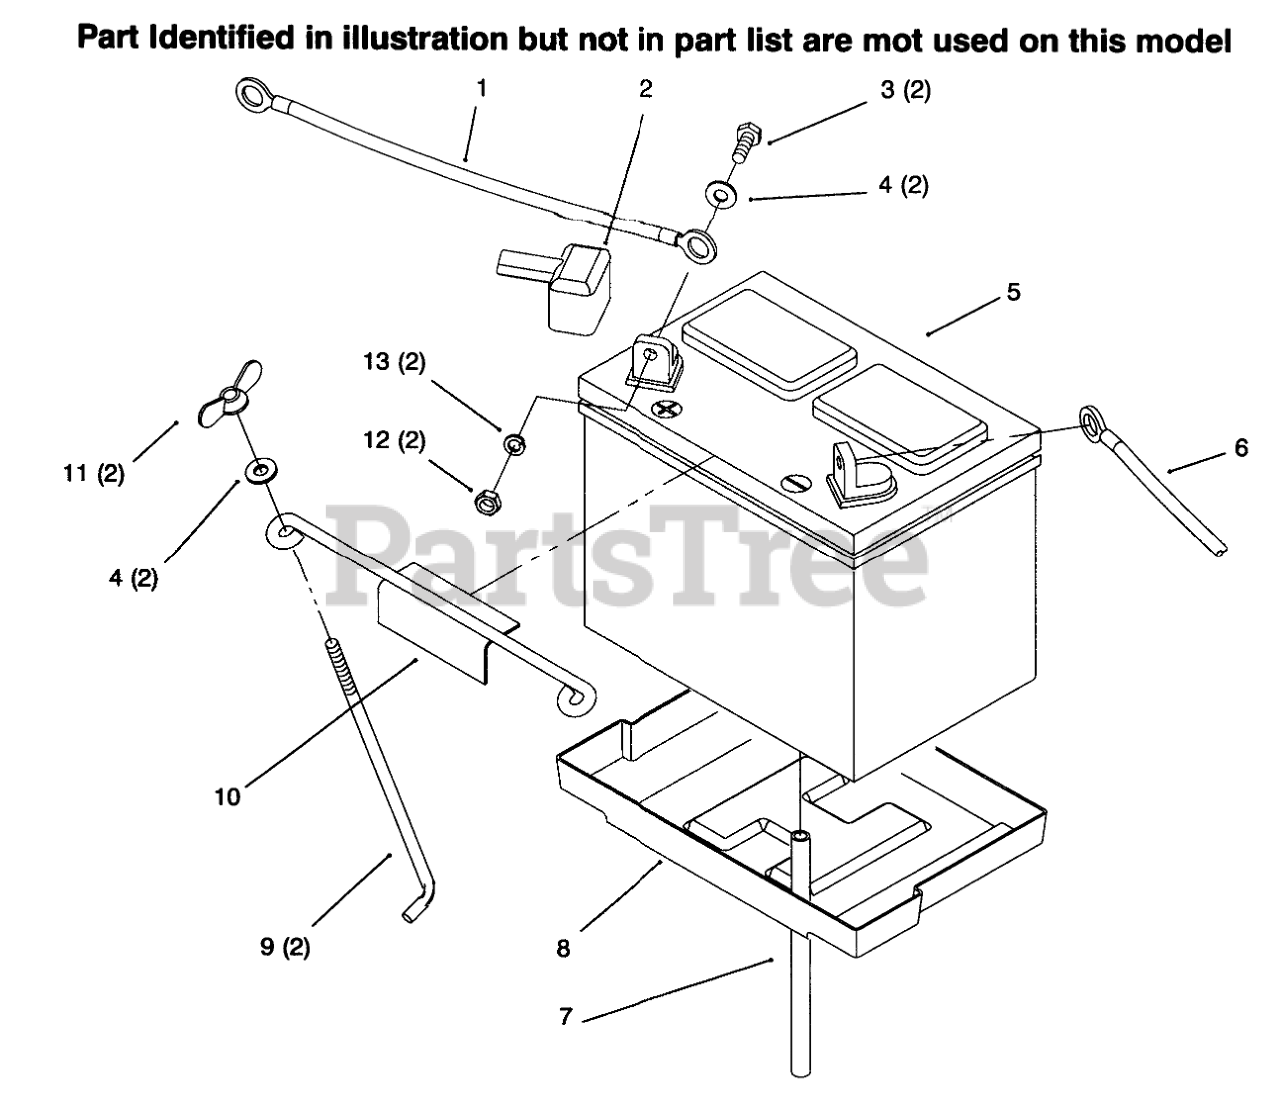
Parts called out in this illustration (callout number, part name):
1	CABLE-BLACK
2	Boot
3	SCREW-HH
4	WASHER-FLAT
5	Battery
6	ASSY WIRE
7	TUBE-21" BATTERY DRAIN
8	TRAY-BATTERY
9	HOOK-BATTERY RETAIN
10	HOLDDOWN-BATTERY
11	NUT-WING
12	NUT-LOCK, NI
13	WASHER-LOCK
